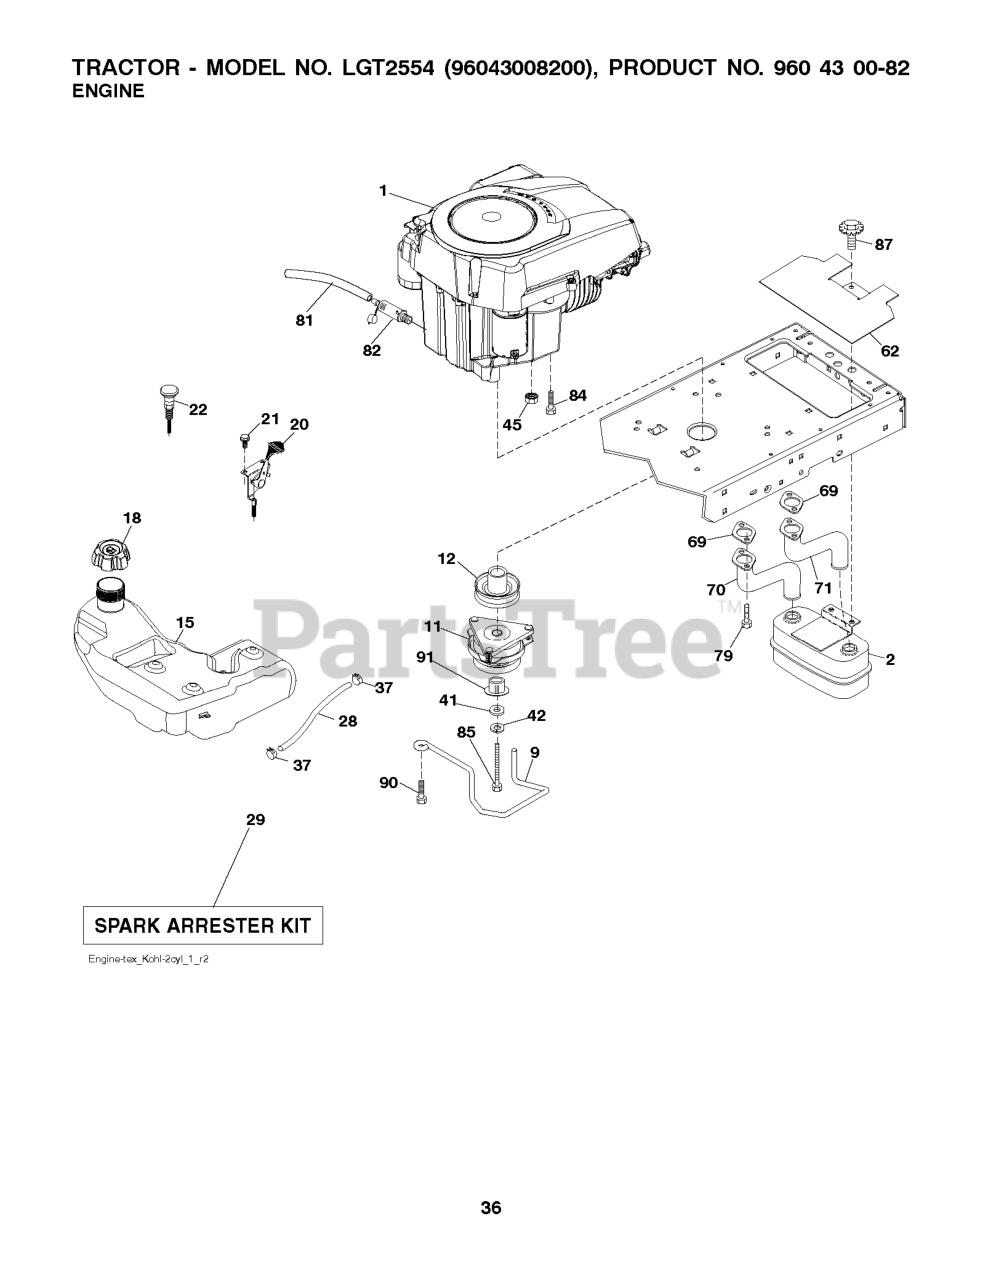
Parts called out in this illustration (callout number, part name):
2	MUFFLER.TWIN.CYL.LOW.TONE
9	KEEPER.BELT.ENGINE.4.2
11	CLUTCH MZ ZTR GT.48/54"1.125"
12	PULLEY ENGINE
15	TANK.FUEL.4GAL
18	CAP.FUEL.TANK.3"GREY
20	THROTTLE CONTROL
21	SCREW.#10 X 0.750.BOS
22	CONTROL.CHOKE.ERGO.PUSH-IN.BLA
28	LINE.FUEL.64"REAR.EMIS
29	KIT.SPARK ARRESTOR 794945 B&S
37	HOSE CLAMP
42	LOCKWASHER
45	NUT
62	RP SHIELD HEAT MUFFLER
69	GASKET.EXHAUST.KOHL.CV18-CV26
70	RP.PIPE-EXHAUST LH
71	RP.PIPE-EXHAUST RH
79	SCREW.SOCKET HD.5/16-1
81	TUBE, DRAIN OIL ASM.
82	PLUG DRAIN OIL EASY
84	SCREW 3/8-16X1
85	BOLT HEX 7/16-20 X 3.75 GR. 5
87	BOLT.5/16-18UNCX1.W/SEMS.BLK
90	SCREW 3/8-16X1
91	BUSHING.1.375OD
